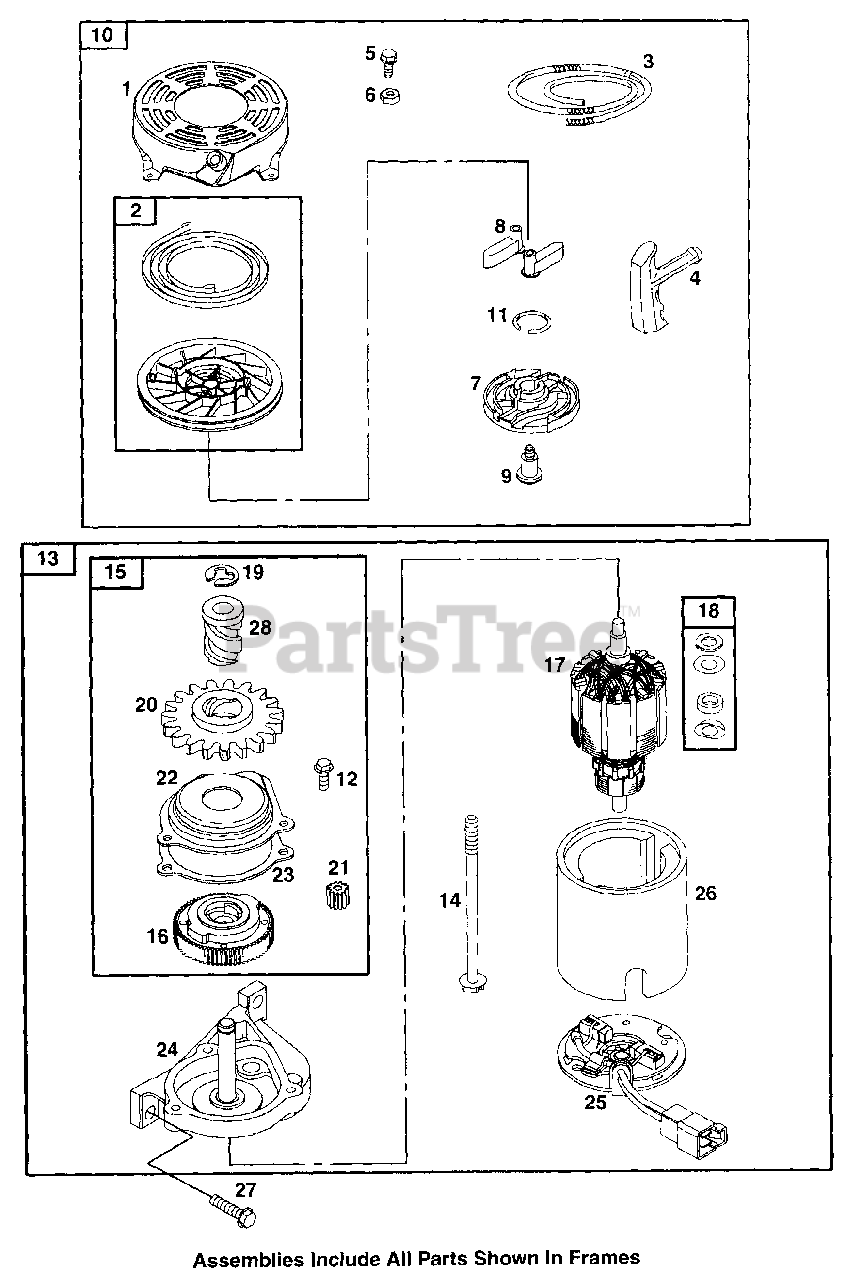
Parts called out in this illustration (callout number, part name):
1	Rewind Starter Housing
2	Starter Pulley
3	Starter Rope
4	Starter Rope Grip
5	Hex Screw
6	Hex Nut
7	Pawl Friction Plate
8	Ratchet Pawl
9	Shoulder Screw
10	Rewind Starter
11	Friction Spring
12	Hex Screw
13	Starter Motor
14	Slotted Hex Screw
15	Starter Drive
16	Drive Clutch
17	Starter Armature
18	Shim Set
19	Retainer
20	Pinion Gear
21	Pinion Gear
22	Gear Cover
23	Cover Gasket
24	Drive Cap
25	End Cap
26	Starter Housing
27	Hex Screw
28	Starter Spline
